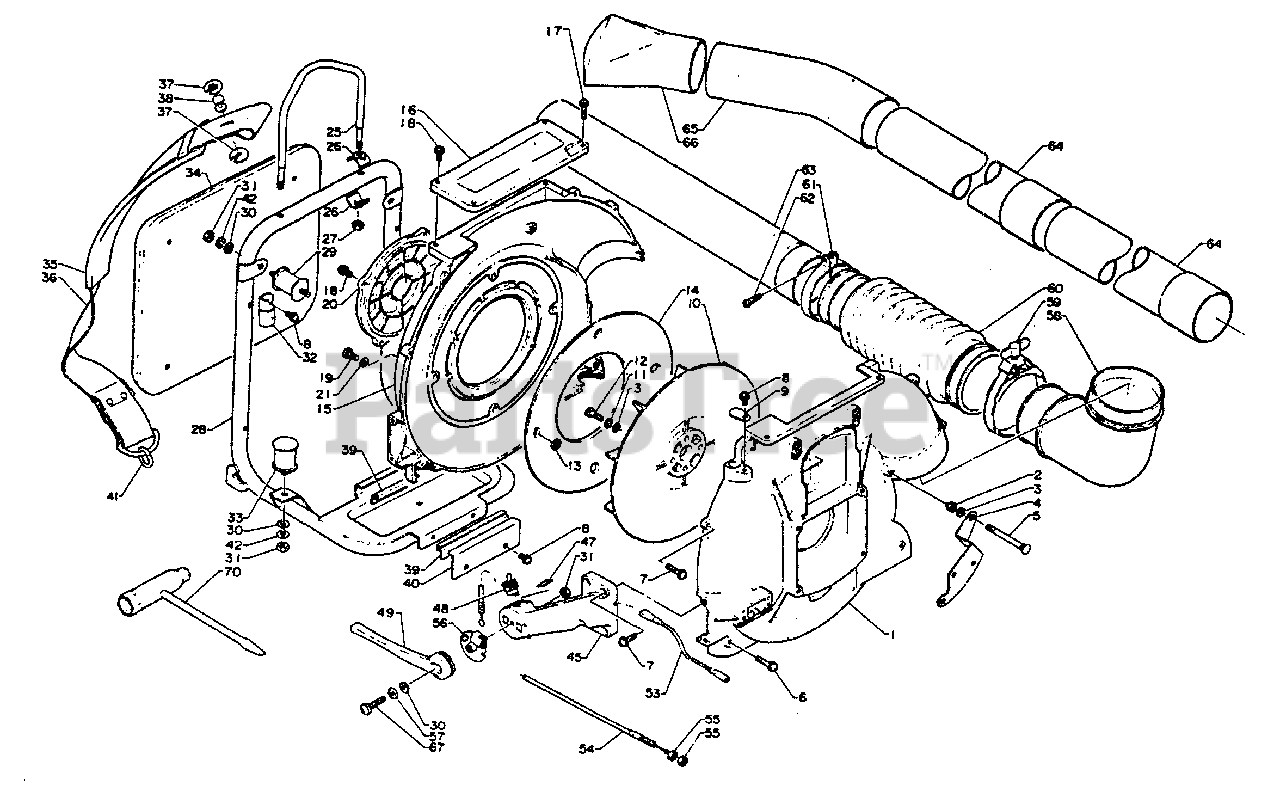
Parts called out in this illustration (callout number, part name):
1	COVER, FAN - OUTER
2	NUT - 5
3	WASHER, FLAT 5.5×10×0.8
4	BRACKET, MUFFLER COVER
6	SCREW 5×25
7	SCREW 5×20
8	SCREW 5×10
9	PLUG
11	WASHER, SPRING 5
12	BOLT - 5×16
14	SEPARATER
15	COVER, FAN - INNER
16	PLATE
17	SCREW 6×20
18	SCREW 6×15
19	BOLT 5×12
20	SHIELD, DEBRIS
21	WASHER 5.3×10×1
27	LOCKNUT - 6
28	FRAME, BACKPACK
30	WASHER 6.5×11.5×0.8
31	NUT, HEX M6
32	BRACKET, CUSHION
34	CUSHION
35	HARNESS
36	BACKPACK STRAP ASSY
37	STRAP ASSY
39	CUSHION, FUEL TANK
40	BRACKET, FUEL TANK
41	RING, STRAP
45	MOUNT, THROTTLE LEVER
47	LABEL, ON-OFF
48	IGNITION SWITCH ASSY
49	TRIGGER, THROTTLE
53	LEAD - GROUND
54	CABLE, THROTTLE
57	WASHER
58	TUBE, BLOWER - ELBOW
60	TUBE, FLEXIBLE
61	CLAMP
62	SCREW 5×20
63	TUBE, BLOWER - STRAIGHT
64	TUBE, BLOWER - STRAIGHT
65	TUBE, BLOWER - CURVED
66	NOZZLE - FAN HEAD
67	SCREW 6×25
70	T-WRENCH 10×19 MM
